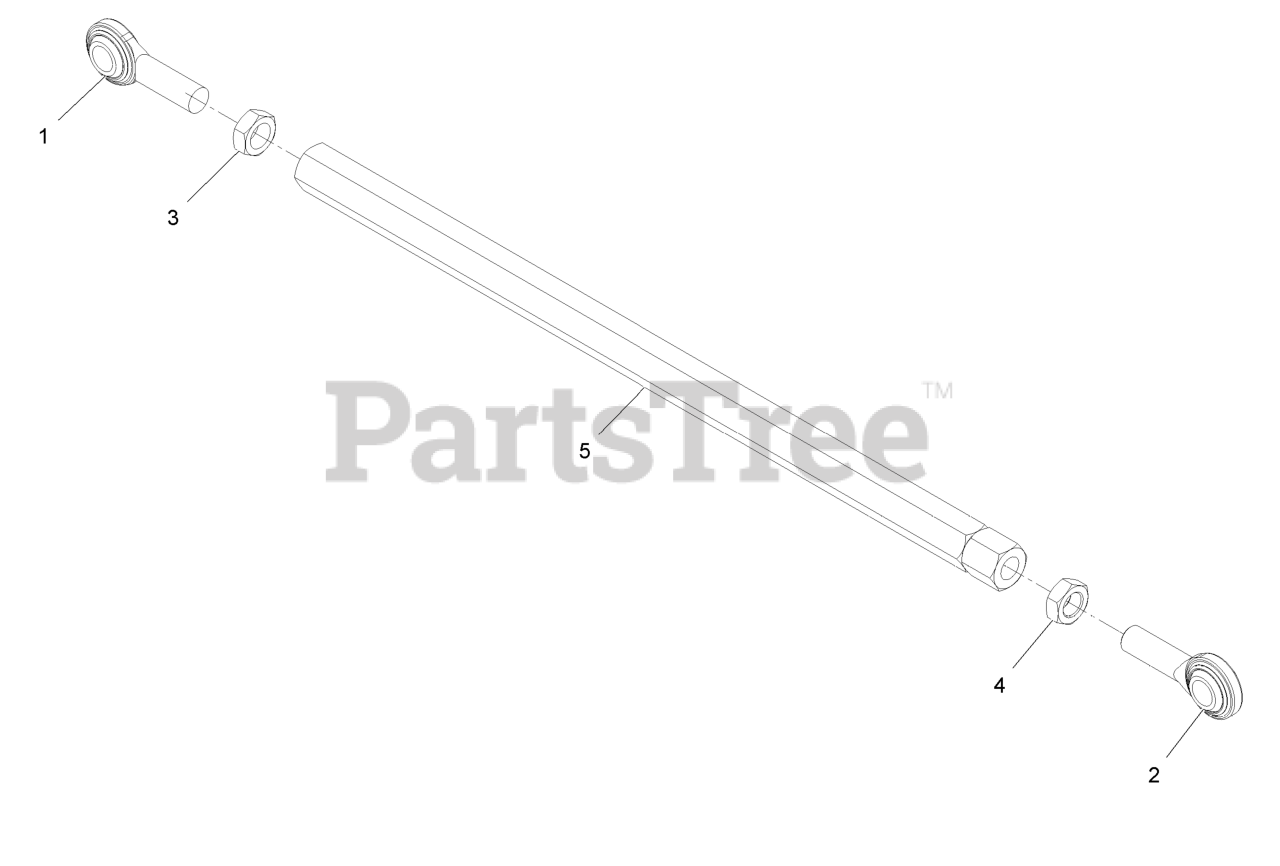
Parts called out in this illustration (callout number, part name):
1	BALLJOINT-SPHERICAL
2	BALLJOINT-SPHERICAL
3	NUT-JAM
4	NUT-JAM
